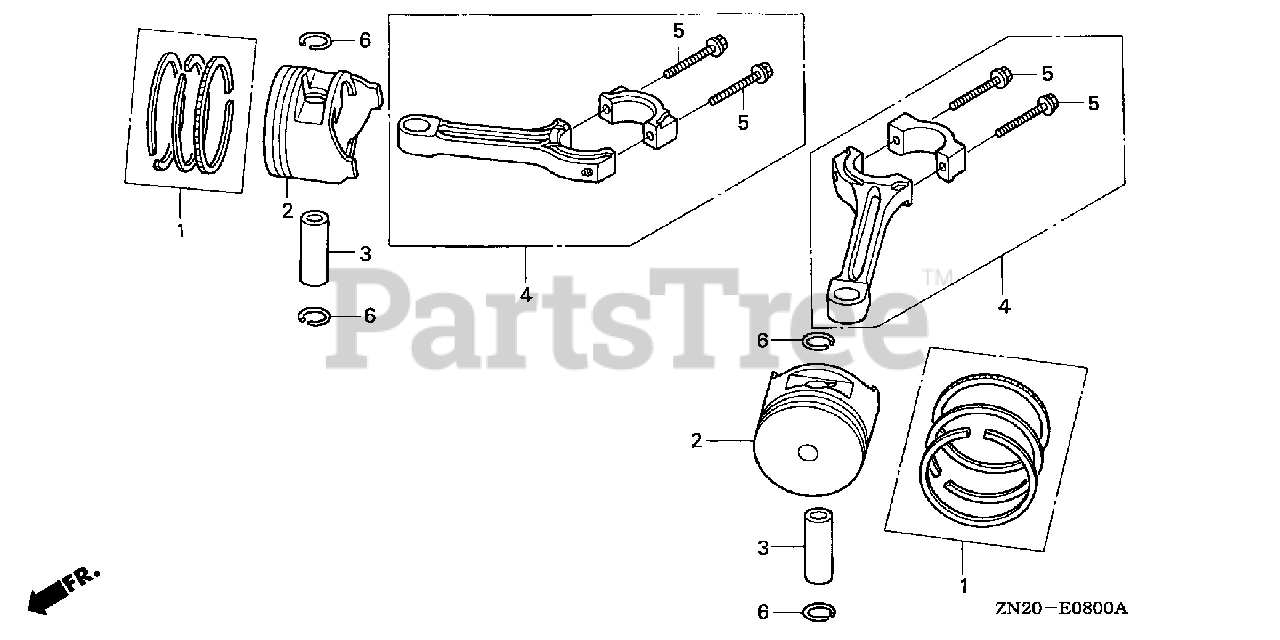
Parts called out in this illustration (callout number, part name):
1	RING SET, PISTON (STD)
1	RING SET, PISTON (OS 0.25)
1	RING SET, PISTON (OS 0.50)
1	RING SET, PISTON (0.75)
2	PISTON (STD)
2	PISTON (OS 0.25)
2	PISTON (OS 0.50)
2	PISTON (0.75)
3	PIN, PISTON
4	ROD ASSY., CONNECTING
5	BOLT, CONNECTING ROD (6X37)
6	CLIP, PISTON PIN (18MM)
